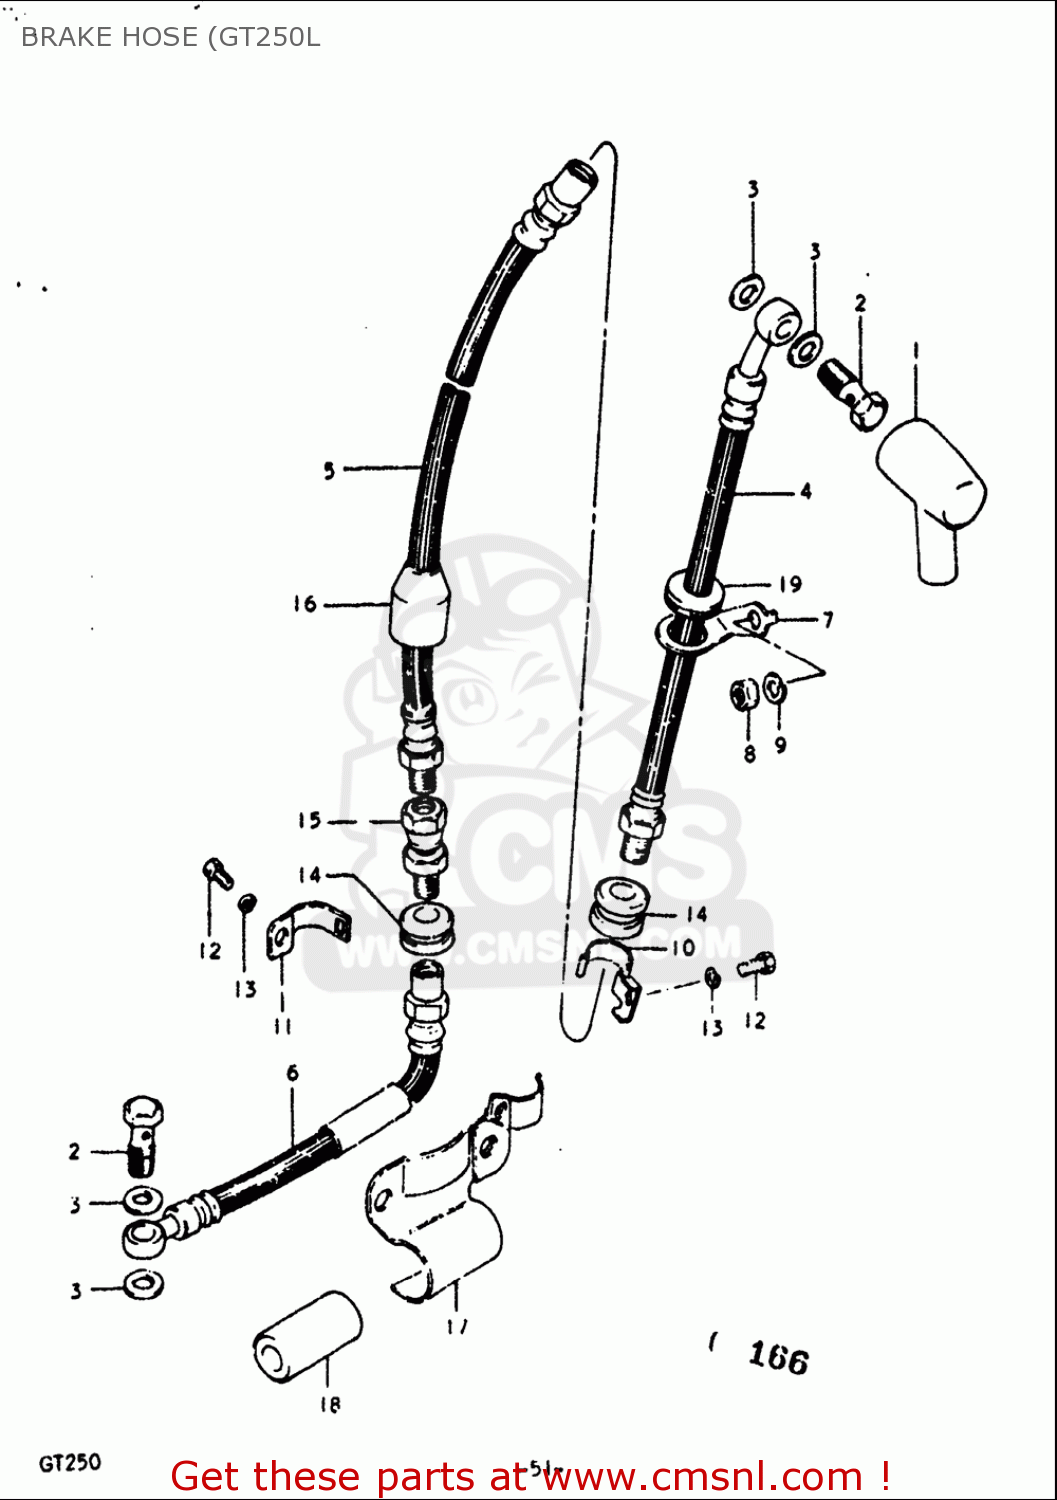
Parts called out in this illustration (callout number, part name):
1	BOOT,MASTER CYLINDER
2	BOLT UNION
3	WASHER(10X15X1.5)
6	HOSE,BRAKE NO.3
8	NUT
9	WASHER,LOCK
12	SCREW(6X12)
13	WASHER,LOCK
14	BUSH
18	CUSHION
19	GROMMET
